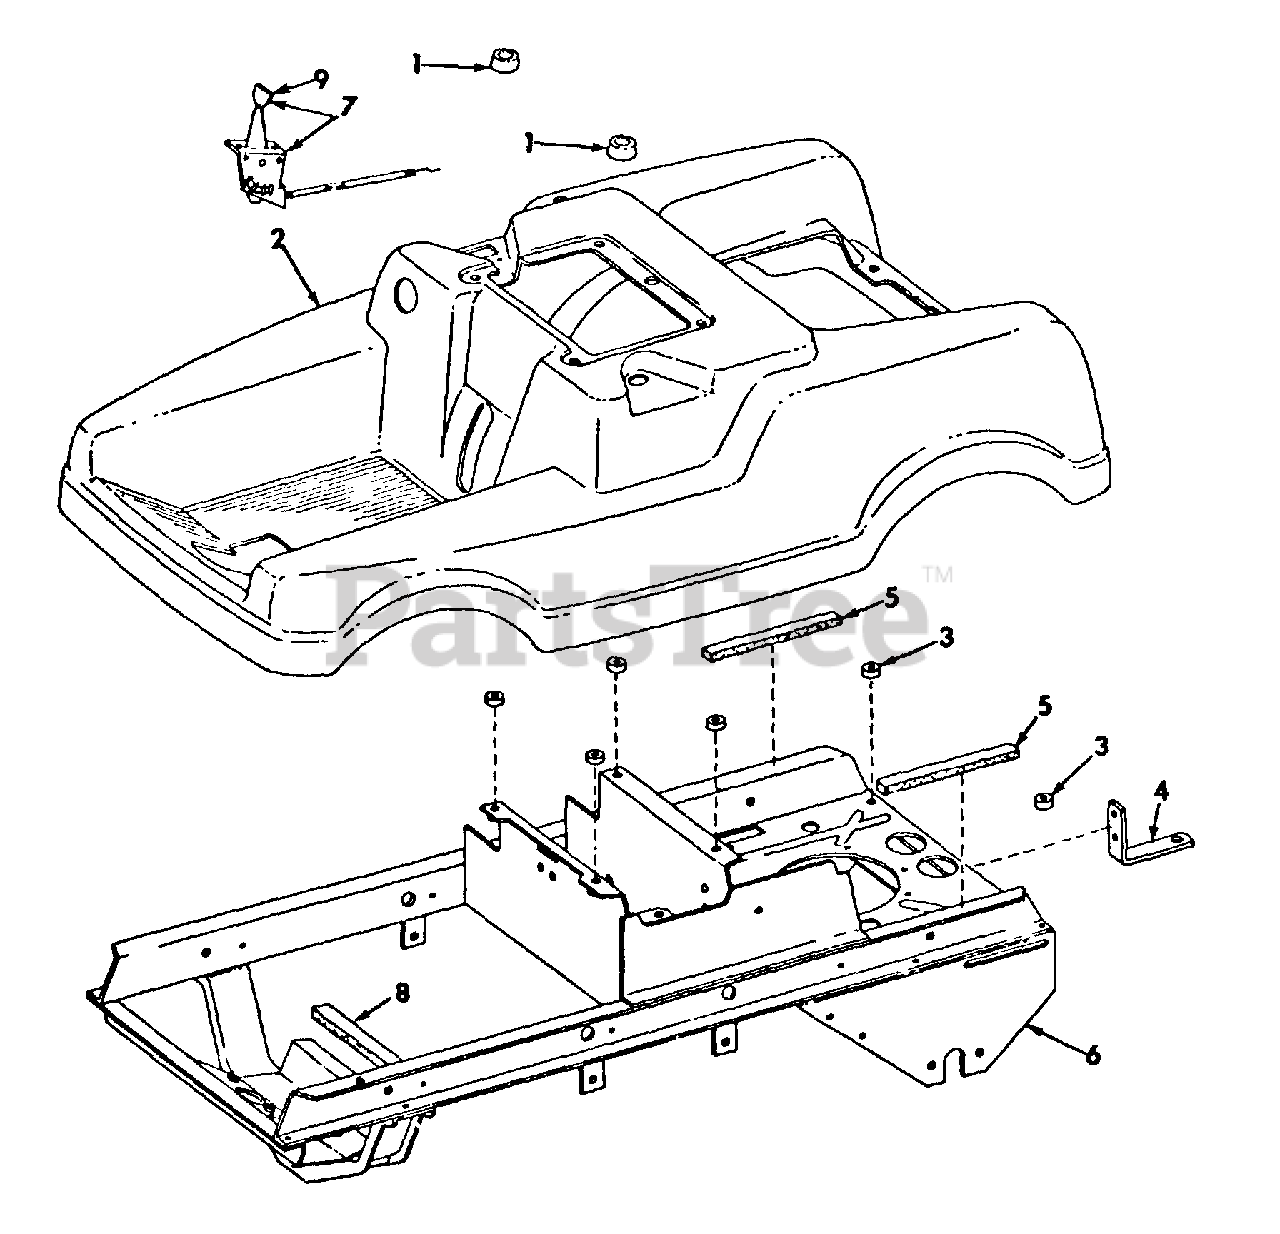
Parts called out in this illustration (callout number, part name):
1	BUMPER, SEAT SUPPORT REAR
2	BODY, RIDING MOWER
3	SPACER, BODY MOUNTING
4	ANGLE, DRAWBAR
5	SEAL, PRESSURIZED
6	FRAME ASSY, MAIL
7	CONTROL ASSY, THROTTLE
8	SEAL, PRESS FRONT REST
9	KNOB, THROTTLE CONTROL
